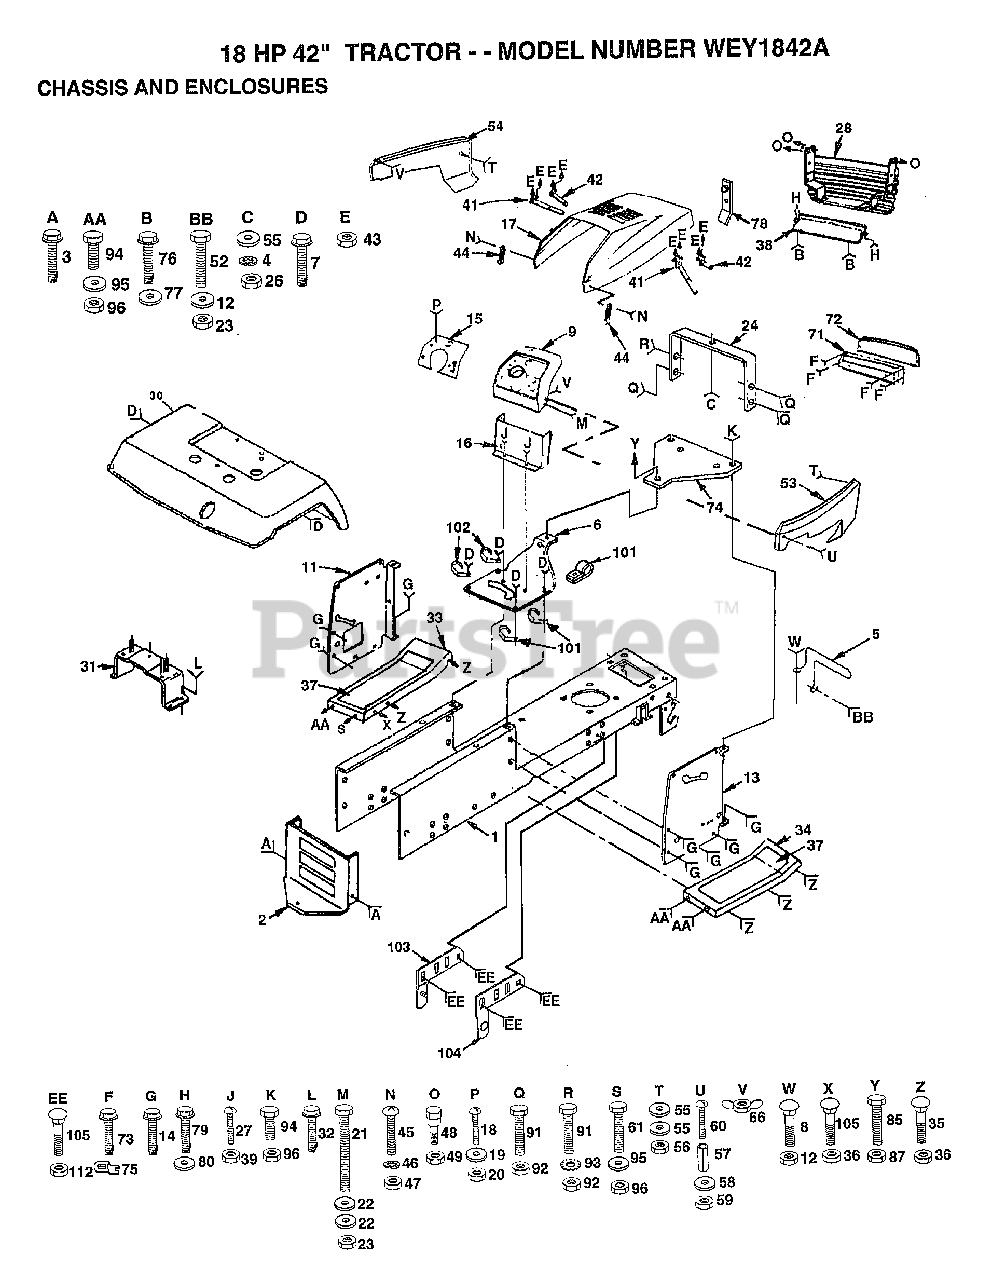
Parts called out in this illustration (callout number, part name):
3	SCREW
4	LOCKWASHER
5	MUFFLER GUARD
6	SADDLE. 6SP
7	SCREW LT
8	SCREW GTV
11	DASH PANEL LH
12	WASHER HYT
14	SCREW
18	SCREW
19	WASHER
22	WASHER
24	SUPPORT ASS'Y
27	SCREW
32	SCREW
35	BOLT
37	"PAD,FOOTREST"
38	"STRAP,GRILL "
43	NUT
44	HOOD LATCH T
45	SCREW
46	LOCKWASHER
47	WELDNUT
52	BOLT D
54	"PANEL,SIDE LH"
55	WASHER PM
57	SPACER LT
58	WASHER
60	SCREW
72	LENS LT
75	"""J"" FASTENER LT"
76	SCREW
77	WASHER
79	SCREW HEX CRT
80	WASHER
85	BOLT
93	LOCKWASHER
95	WASHER
101	CLIP T
102	"CLIP,INSULATOR"
103	PIVOT BRKT LH
104	PIVOT BRKT RH
112	NUT
